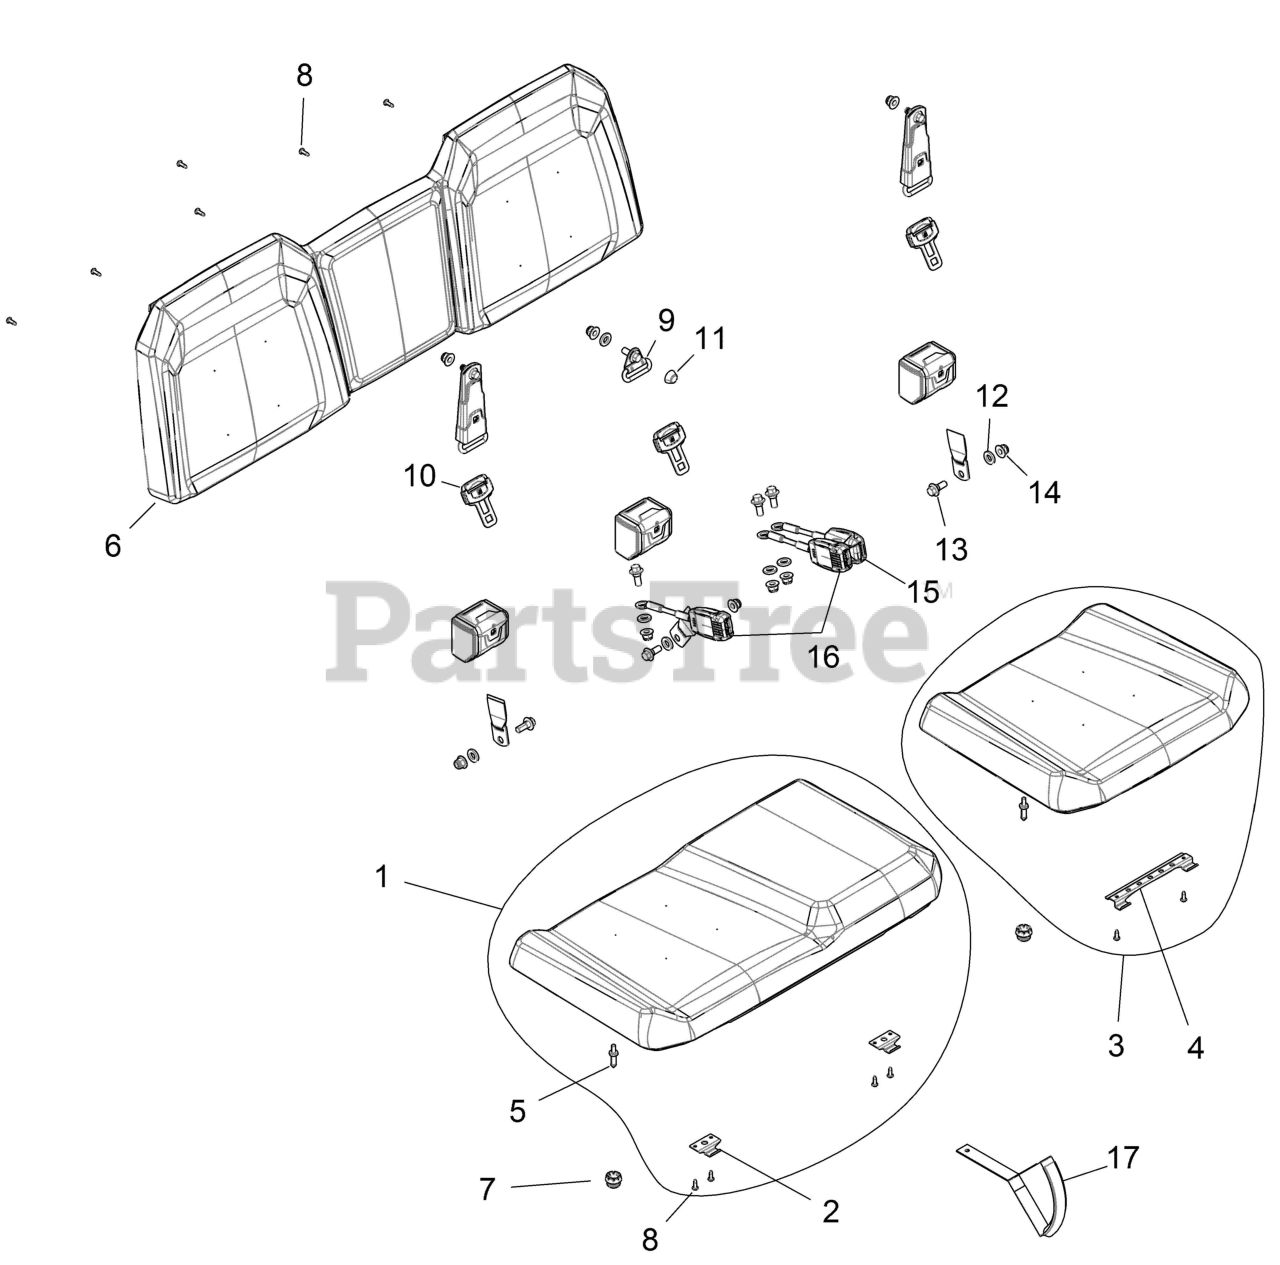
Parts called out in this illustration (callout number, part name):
1	ASM,SEAT,BTM,60,GRVLY GRAY
2	BRKT-SEAT HINGE
4	BRKT-SEAT HINGE,DOUBLE
5	PIN-SEAT LATCH
6	ASM,SEAT,3PASS,BACK,GRVLY,GRAY
8	SCR-TX TRUSS-#14X3/4,HI/LO ZBK
9	ASM-SEAT BELT,3PT,CENTER
10	ASM-SEAT BELT,3PT
11	CAP, BOLT HEAD
12	WASHER-SEATBELT,RUBBER
13	SCR-HXFLSH-M12X1.75-M14X9 ZOD
14	NUT-HXFL M12X1.75 NYLOC ZOD
15	BUCKLE, SEATBELT, 90, SWITCH
16	BUCKLE-SEATBELT,9.6,PASSENGER
17	STRAP, SEAT, CENTER
